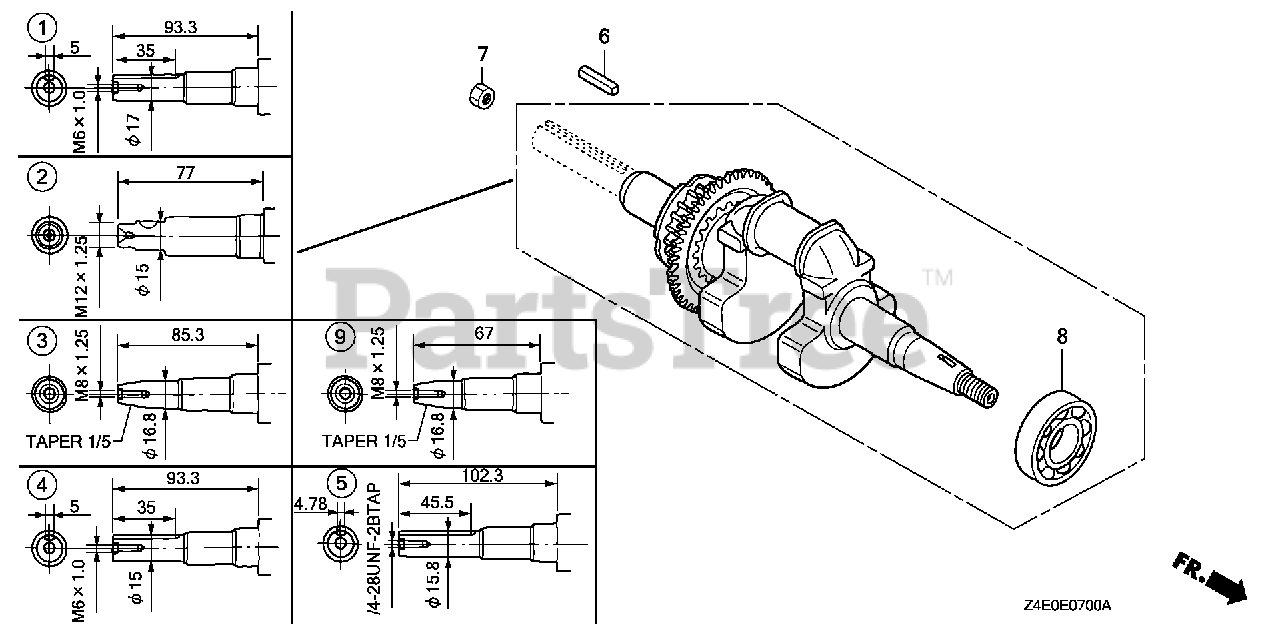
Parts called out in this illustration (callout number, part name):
4	CRANKSHAFT
6	KEY (5X5X33)
8	BEARING, RADIAL BALL (6204)
